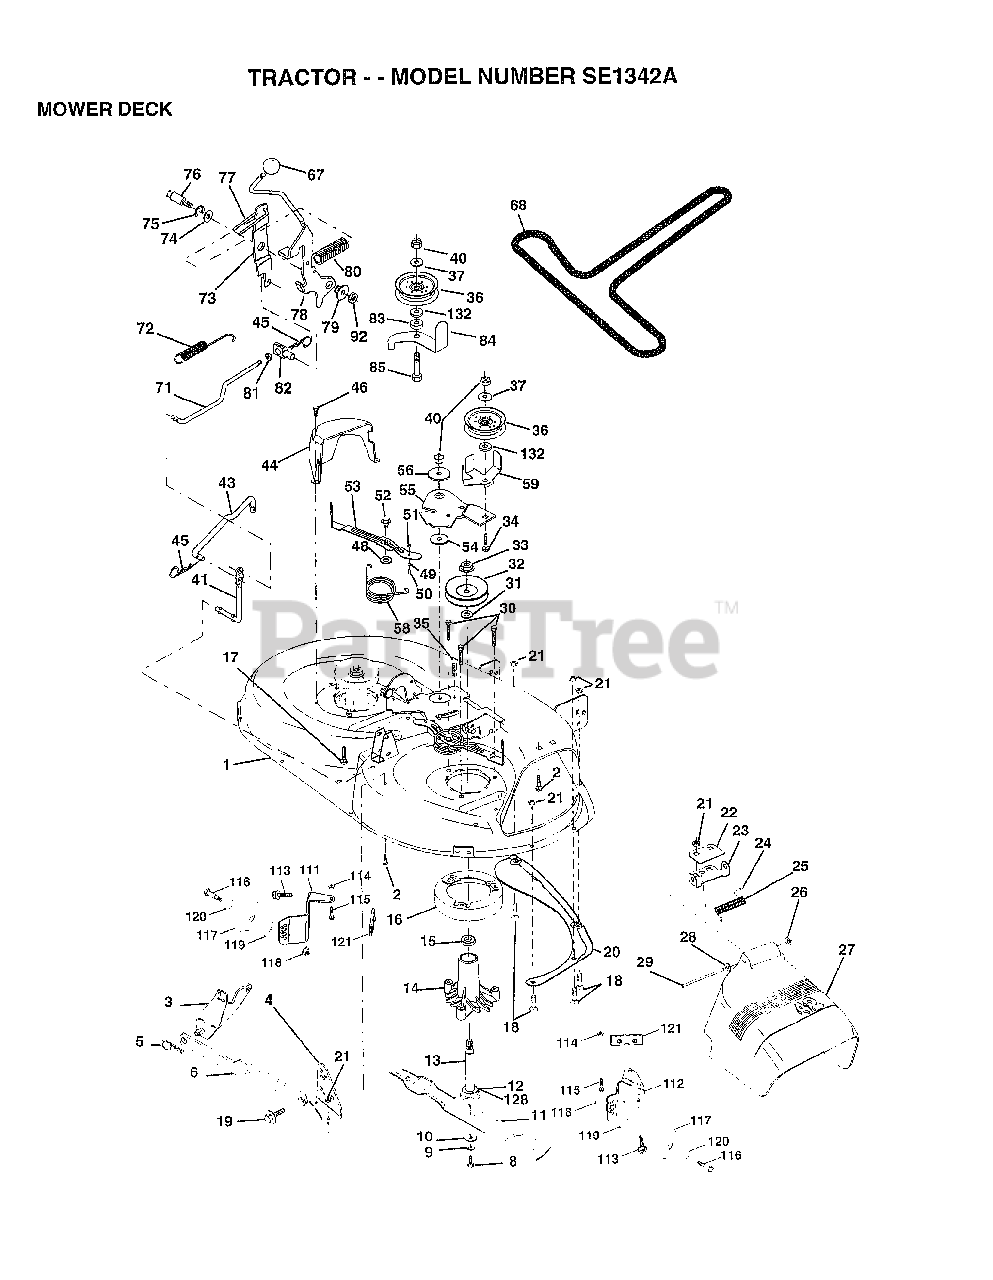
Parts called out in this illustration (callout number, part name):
1	DECK.WELD.42.
2	BOLT
3	BRKT ASM SWAY BAR
4	BRKT DECK SW BAR
8	BLADE BOLT
10	WASHER.HARD.BLADE
11	"BLADE.42"" HIPERF"
12	BEARING.BALL
14	HSG ASM MANDREL
15	BEARING
16	STRIPPER RND MWR
17	BOLT RDHD 3/8-16
18	BOLT
19	BOLT SHD 5/16-18
22	STIFFENER BRKT
23	DEFLECTOR BRKT
24	CAP-SLEEVE LT
25	SPRING TORSION
27	DEFLECTOR.SHIELD
28	WASHER
29	HINGE ROD
30	"SCREW-THD ROLL,WA"
31	WASHER
32	PULLEY.MANDREL.42
34	BOLT
35	XMAS TREE FASTNER
36	FLAT IDLER PULLEY
37	WASHER
41	PIVOT ROD
43	ROD CLUTCH W/NIBS
44	GUARD MAND LH BLK
46	SCREW.1/4-20X5/8
48	HARD SMALL WASHER
49	ROLLER ASM-CAM
50	SHOULDER BOLT
51	LOCKNUT
52	BOLT.SHLD.5/16-18
54	HARDENED WASHER
55	ARM-IDLER
56	SPACER RETAINER
58	SPRING TORSN BRAK
59	GUARD IDLER TUV
67	KNOB T(3/8 HOLE)
68	BELT.V.T-PATH
71	ROD CLUTCH 38/42
72	RETURN SPRING
73	CLUTCH ARM SECOND
74	WASHER
75	RING
76	SHOULDER BOLT
77	SPRING KEEPER
78	LEVER ASM-CLUTCH
79	BUSHING
80	SPRING.CLUTCH.MWR
81	NUT
82	TRUNION ADJ
83	WASHER
84	"KEEPER-BELT,FIXED"
85	BOLT RDHD 3/8-16
92	NUT
111	BRACKET.GWHL.LH.
112	BRACKET.GWHL.RH.
113	SCREW
116	BOLT M
117	WHEEL.GAGE.BLK.PL
118	LOCKNUT
119	WASHER
120	WASHER
121	BRACKET.EXTRD.GWL
128	WASHER.FELT.
132	WASHER GT
